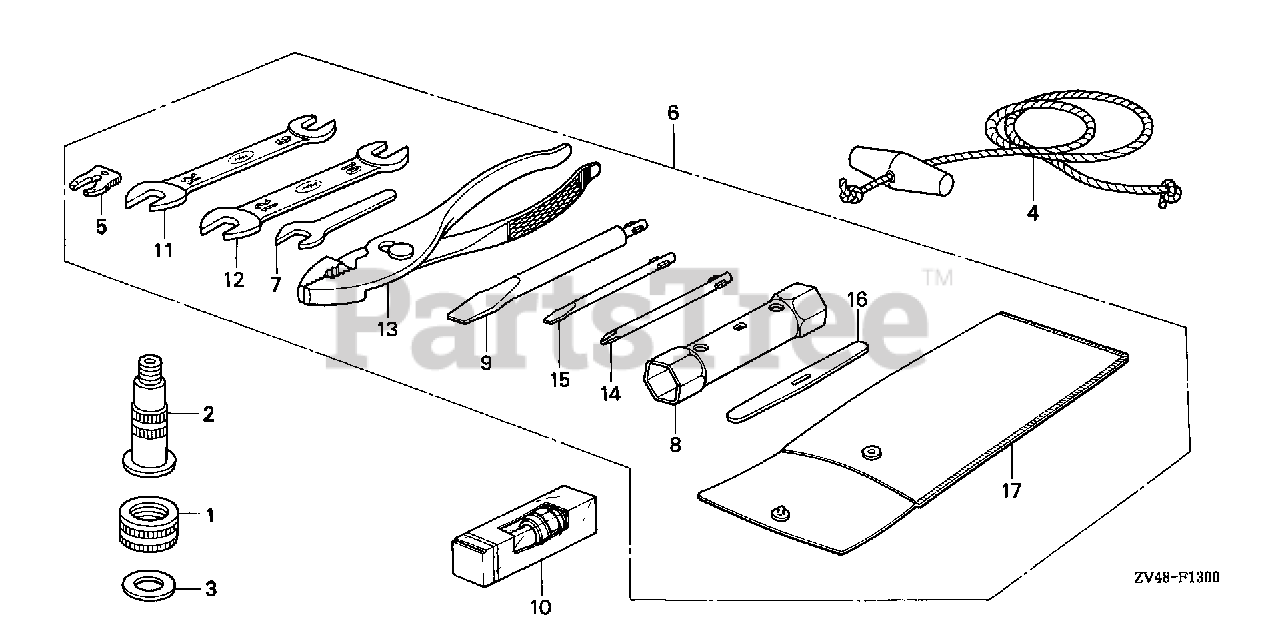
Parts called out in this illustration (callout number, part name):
1	NUT, WATER MOUTH
2	JOINT, WATER HOSE
3	SEAT, WATER MOUTH
4	ROPE, STARTER
5	CLIP, EMERGENCY LOCK
6	TOOL KIT (N/A: SEE COMPONENTS)
7	SPANNER (8MM) (NOT AVAILABLE)
8	WRENCH, BOX (P18X19) (NOT AVAILABLE)
9	SCREWDRIVER, CHECK BOLT
10	SPARK PLUG (DR6HS) (NGK)
10	SPARK PLUG (X20FSR-U) (DENSO)
11	SPANNER (9X12)
12	SPANNER (10X12)
13	PLIERS (135)
13	PLIERS (135) (KOWA)
14	DRIVER 1, PLUS SCREW (NO.2)
15	DRIVER 3, MINUS SCREW (NO.2)
